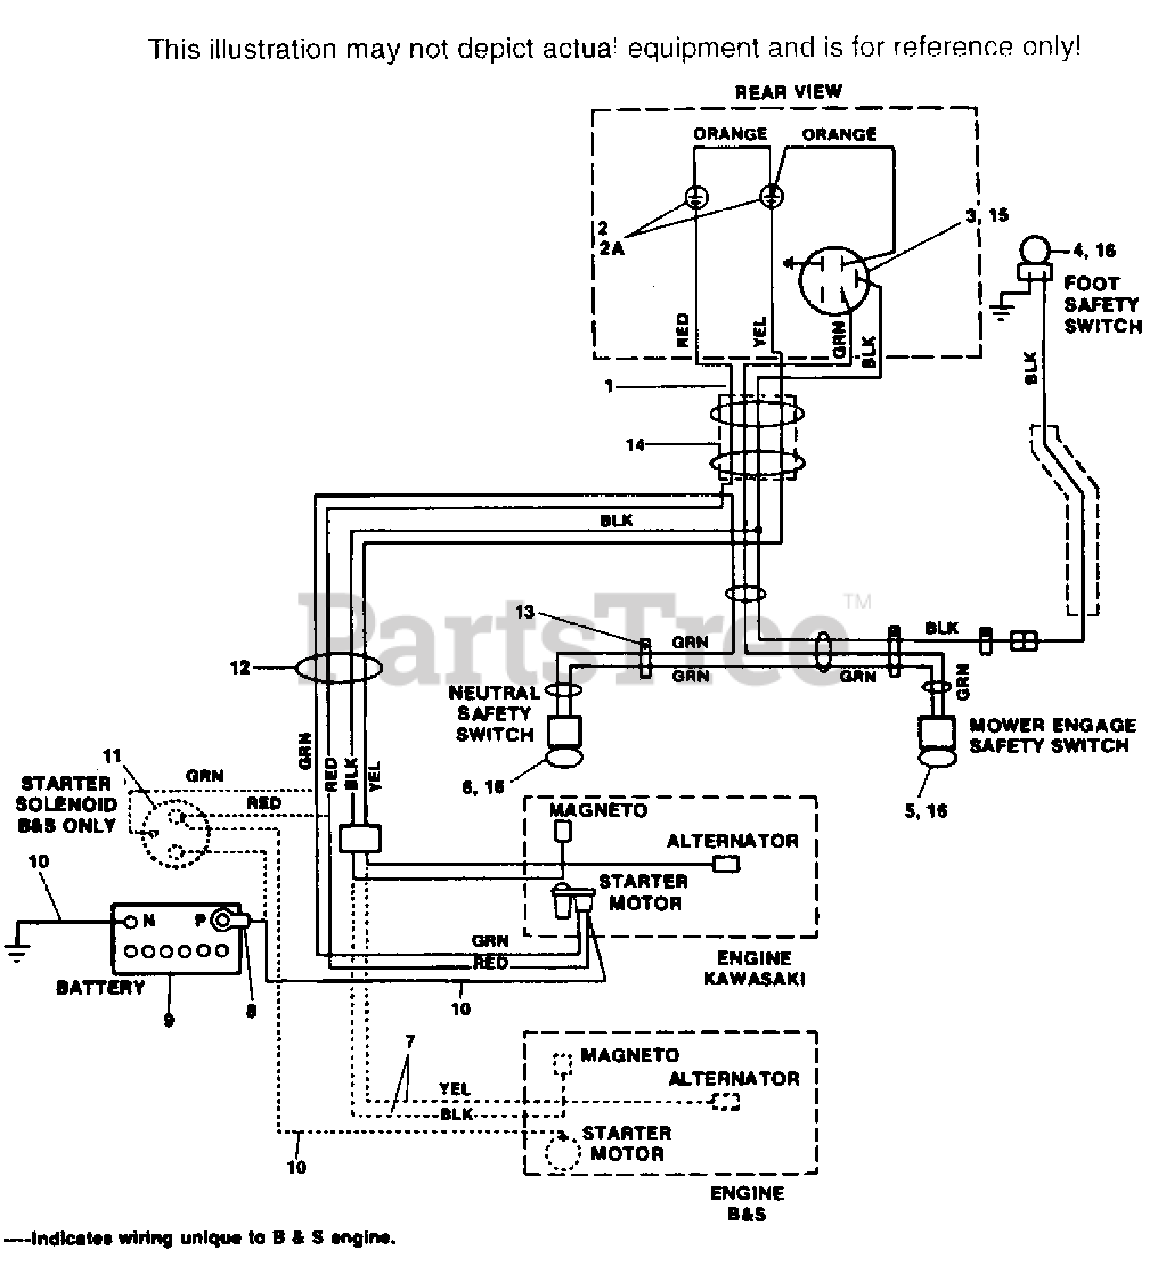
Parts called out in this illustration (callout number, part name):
1	WIRING HARNESS, COMPLETE
2	FUSE HOLDER
2A	FUSE
3	KEY SWITCH
4	FOOT SAFETY SWITCH
5	MOWER ENGAGE SAFETY SWITCH
6	NEUTRAL SAFETY SWITCH
7	HARNESS ADAPTER, B&S ONLY
8	RUBBER BOOT
9	BATTERY
10	BATTERY CABLE
10	BATTERY CABLE, RED
11	STARTER SOLENOID, B&S ONLY
12	CABLE TIE
13	CABLE CLAMP
14	PLASTIC CONDUIT
15	CONNECTOR, STARTER SWITCH
16	CONNECTOR, SAFETY SWITCH
